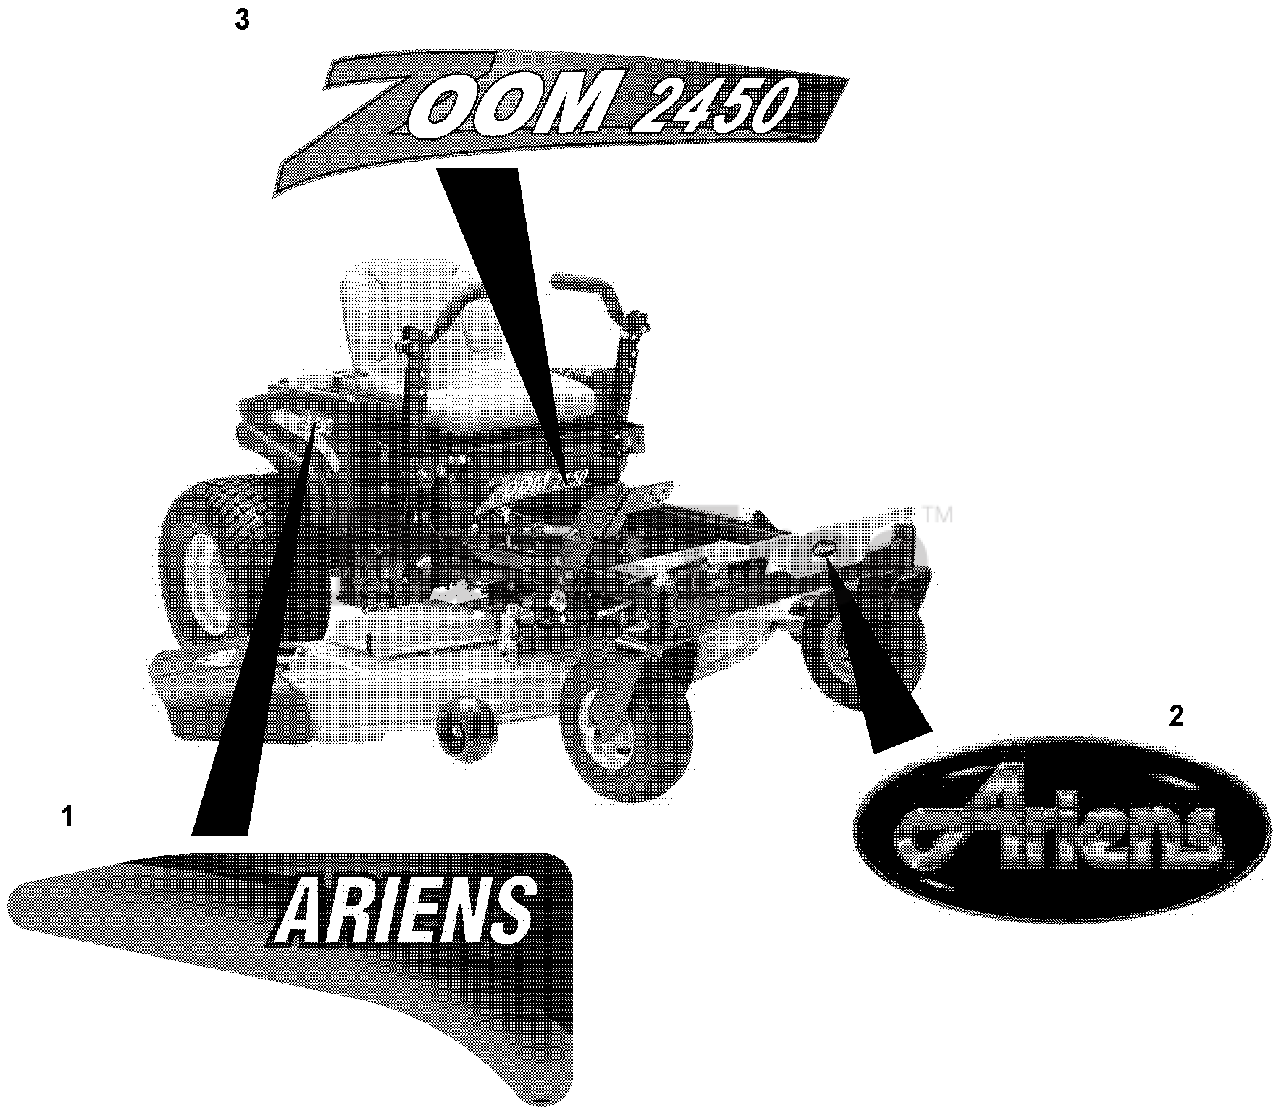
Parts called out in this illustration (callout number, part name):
1	DECAL, RH ARIENS ZOOM TANK
1	DECAL, LH ARIENS ZOOM TANK
2	DECAL-ARIENS JEWEL
3	DECAL, ZOOM 2450
3	DECAL, 1840 ZOOM
3	DECAL, 1634 ZOOM
3	DECAL, 2150 ZOOM
